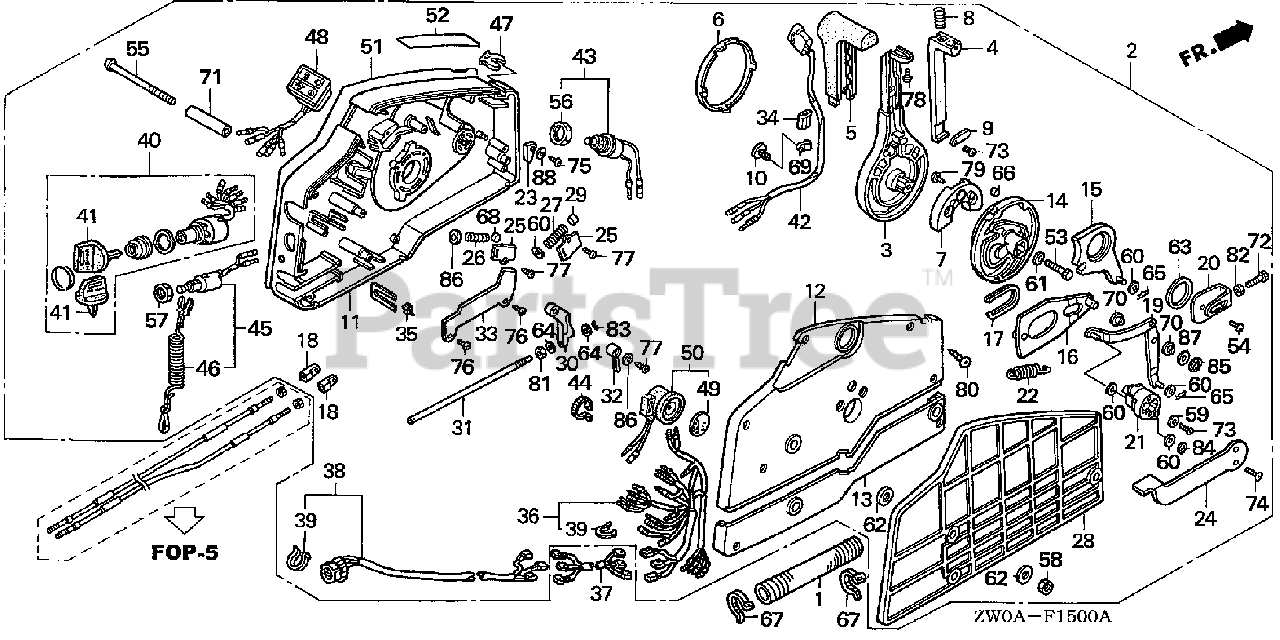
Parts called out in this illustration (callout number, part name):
1	TUBE, CORRUGATE (28MM)
2	BOX ASSY., REMOTE CONTROL
3	HANDLE, REMOTE CONTROL
4	LEVER, HANDLE LOCK
5	GRIP, REMOTE CONTROL HANDLE
6	CAP, HANDLE
7	BLOCK, NEUTRAL LOCK
8	SPRING, REMOTE CONTROL HANDLE
9	PLATE, LEVER SETTING
10	CLAMP, HARNESS
11	HOUSING, REMOTE CONTROL BOX
12	HOUSING, REMOTE CONTROL BOX
13	HOUSING, REMOTE CONTROL BOX
14	WHEEL, CONTROL
15	ARM, SHIFT LINK
16	PLATE, SLIDING
17	COLLAR, SLIDING PLATE
18	PIVOT, SHIFT
19	ARM, LINK JOINT
20	BRACKET, LINK JOINT
21	WHEEL, ACCELERATOR
22	SPRING, ACCELERATOR WHEEL
23	CAM, STARTER SWITCH
24	LEVER, IDLE
25	PLATE, SPRING SETTING
26	SPRING, SHIFT CLICK
27	SPRING, CHOKE RETURN
28	SPACER, REMOTE CONTROL BOX
29	SPACER, CLICK SPRING
30	BLOCK, THROTTLE FRICTION
31	BOLT, FRICTION
32	SPACER, NEUTRAL SWITCH
33	CLAMP, POWER TILT CORD
34	PIPE, HARNESS GUIDE
35	SPACER, CABLE CLAMP
36	CABLE ASSY., REMOTE CONTROL
37	CABLE ASSY., REMOTE CONTROL
38	CABLE ASSY., SWITCH PANEL
39	TIE, CABLE (NATURAL 2.4X92)
40	SWITCH ASSY., COMBINATION
41	KEY ASSY., COMBINATION SWITCH
42	SWITCH ASSY., POWER TRIM-TILT
43	SWITCH ASSY., SOLENOID
44	BAND (BLACK 3.5X140)
45	SWITCH ASSY., EMERGENCY STOP
46	WIRE, EMERGENCY
47	CLIP, EMERGENCY LOCK
48	LAMP ASSY., INDICATION (2-LED)
49	PLATE, TURN SIGNAL BUZZER
50	BUZZER, WARNING
51	PLATE, REMOTE CONTROL
52	MARK, FAST IDLE
53	BOLT, HEX. (8X35)
54	SCREW, PAN (6X10)
55	SCREW (6X95)
56	NUT, HEX. (20MM)
57	NUT, HEX. (16MM)
58	NUT, HEX. (6MM)
59	WASHER, PLAIN (5MM)
60	WASHER, PLAIN (6MM)
61	WASHER, PLAIN (8MM)
62	WASHER (6MM)
63	WASHER (28MM)
64	WASHER, PLAIN (4MM)
65	PIN, LOCK (6MM)
67	BAND, SELF-LOCK
68	ROLLER, CLICK
69	CLIP, WIRE HARNESS (6.3MM)
70	COLLAR, LINK JOINT
71	COLLAR, DISTANCE (6X10X43.5)
72	BOLT, HEX. (5X16)
73	SCREW, PAN (5X10)
74	SCREW, OVAL (5X12)
75	SCREW, TAPPING (4X10)
76	SCREW, TAPPING (5X8)
77	SCREW, TAPPING (5X10)
78	SCREW, TAPPING (5X12)
79	SCREW, TAPPING (6X16)
80	SCREW, TAPPING (5X25)
81	NUT, HEX. (6MM)
82	NUT, HEX. (5MM)
83	E-RING (3MM)
84	E-RING (4MM)
85	E-RING (7MM)
86	WASHER, PLAIN (5MM)
87	WASHER, PLAIN (8MM)
88	WASHER, PLAIN (4MM)
